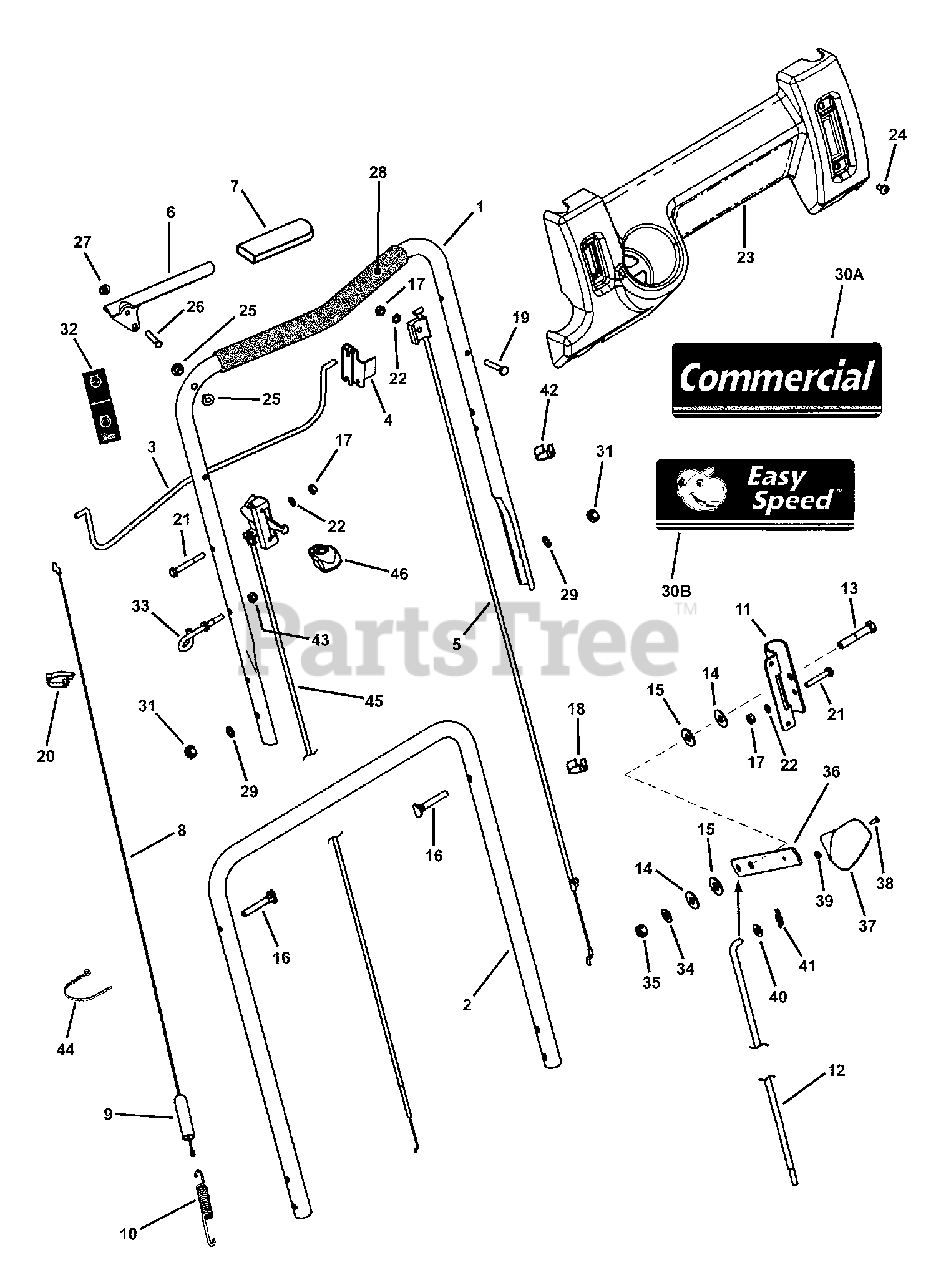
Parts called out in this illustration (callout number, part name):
1	HANDLE, Upper
2	HANDLE, Middle
3	BAIL, OPC Control
4	CLIP, Zone Control
5	CABLE, Zone Control (56-5/16" Long)
5	CABLE, Zone Control (60.3" Long)
6	HANDLE, Clutch
7	COVER, Grip, Black 1.125"
7	GRIP, International Symbol, Black 4.6"
8	CABLE, Clutch Control (41-1/4" Long)
9	COVER, Vinyl
10	SPRING, Clutch- 21S
11	BRACKET, Shift
12	ROD, Speed Control (1/4-28 thread)
13	SCREW, 3/8-16 x 2" Hex Head Cap, GR 5
14	WASHER, 7/16" Flat
15	WASHER, Nylon
16	BOLT, 5/16-18 x 1-1/2" Curved Head
17	NUT, 1/4-20 Hex
18	CLIP, Wiring Harness
19	SCREW, 1/4-20 x 1-1/2" Hex Head Cap GR5
20	CLAMP, 7/8" Double Cable
21	SCREW, 1/4-20 x 2" Hex Head Cap, GR 5
22	WASHER, 1/4" Internal Tooth Lock
23	CONTROL PANEL (w/o Electrical Switch Hole)
24	SCREW, 1/4-20 x 1/2" Pan Head Self-Tap (Torx)
25	BUSHING, .27 x .35 x .4 Flange
26	PIN, 1/4 x 1-1/2"
27	PUSH-NUT, 1/4"
28	FOAM GRIP, 18.75" long
29	WASHER, 5/16" Internal Tooth Lock
30A	DECAL, Commercial, Control Panel
30B	DECAL, Control Panel, Easy Speed
31	NUT, 5/16-18 Hex, GR 5
32	DECAL, OPC Bail (International Symbol)
33	GUIDE, Rope (1/4-20 thread)
34	WASHER, Belleville
35	NUT, 3/8-16 Hex Center Lock
36	LEVER, Shift
37	KNOB, Shift
38	SCREW, #8-32 x 1/2" Cross Recess Filister Head Machine
39	NUT, #8-32 Hex
40	WASHER, 3/8" Flat
41	COTTER PIN, 5/16 Self Lock
42	TIE, Wire, 1.29 long, black
43	NUT, 1/4-28 Hex Nyloc
44	CABLE-TIE, 7"
45	THROTTLE CONTROL, 5.5 HP, Honda (50.81" long)
45	THROTTLE CONTROL, 6.0 HP Kawasaki (53.25" long)
46	THROTTLE KNOB
